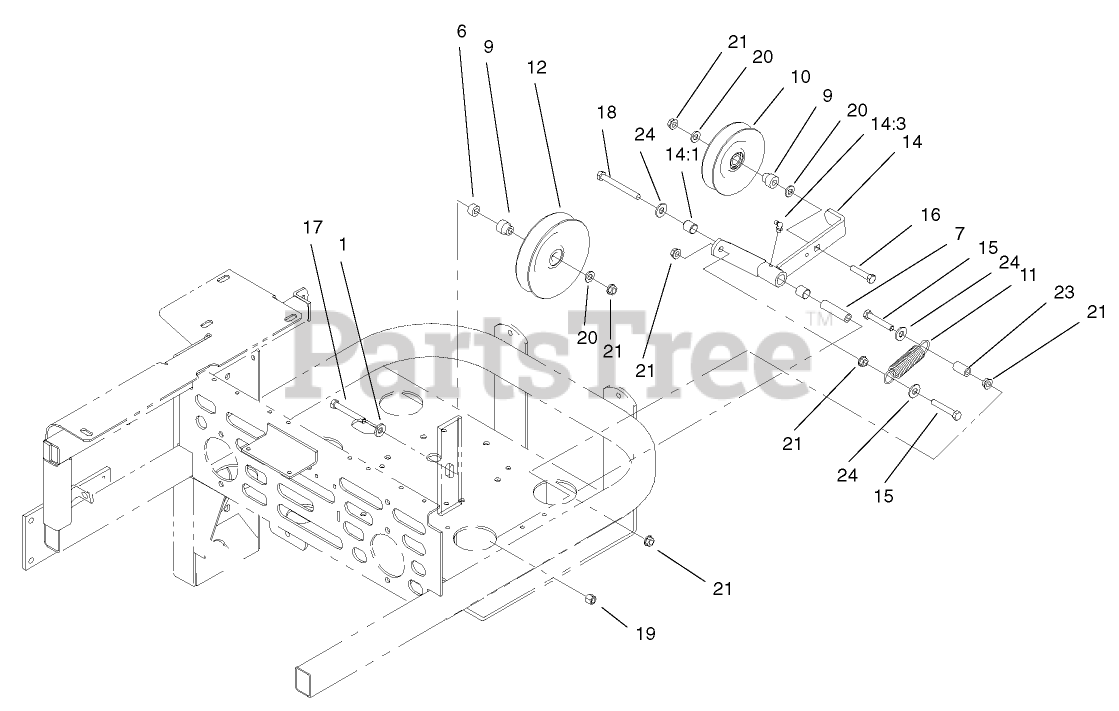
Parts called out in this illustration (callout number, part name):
1	WASHER-BELLEVILLE
6	SPACER
7	BUSHING-PIVOT, IDLER
9	BUSHING-IDLER
10	Idler
11	SPRING-EXTENSION
12	PULLEY-IDLER
14	IDLER ARM ASM
14:1	SLEEVE-BEARING
14:3	FITTING-GREASE, 90 DEG
15	SCREW-HH
16	SCREW-HH
17	SCREW-HH
18	SCREW-HH
19	NUT-LOCK, NI
20	WASHER-FLAT
21	NUT-HHF, WHIZ
23	SPACER
24	WASHER-FLAT
